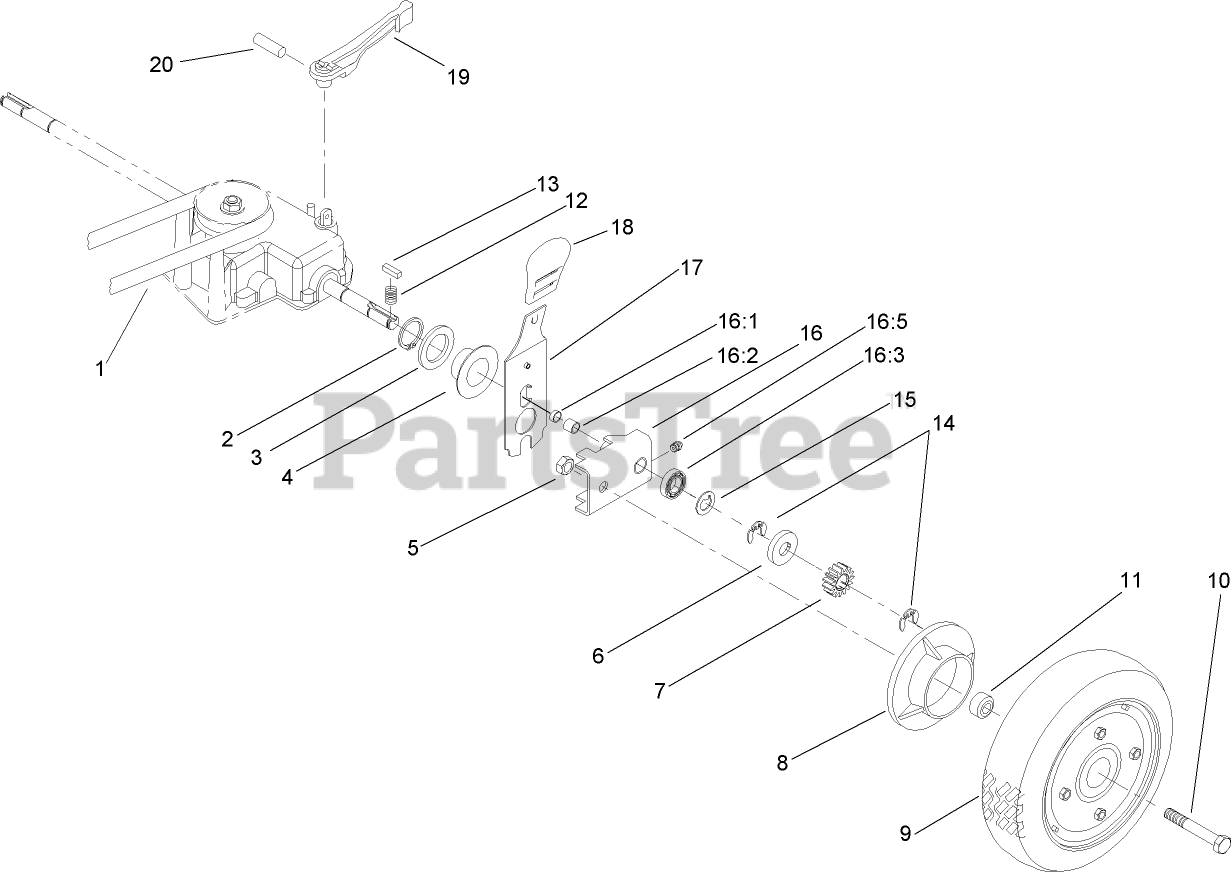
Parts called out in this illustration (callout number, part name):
1	V-BELT
2	RING-RETAINING
3	WASHER
4	CAP-END
5	NUT-LOCK, CONE
6	WASHER-THRUST, OUTER
7	GEAR-PINION
8	COVER-WHEEL
10	SCREW-HH
11	SPACER-COVER, WHEEL
12	SPRING-COMPRESSION
14	RING-RETAINING
15	WASHER-THRUST, OUTER
16	PIVOT ARM ASM
16:1	SEAL-OIL
16:3	BEARING-WHEEL
18	KNOB-HOC
19	LEVER-SHIFT
20	PIN-SPRING
